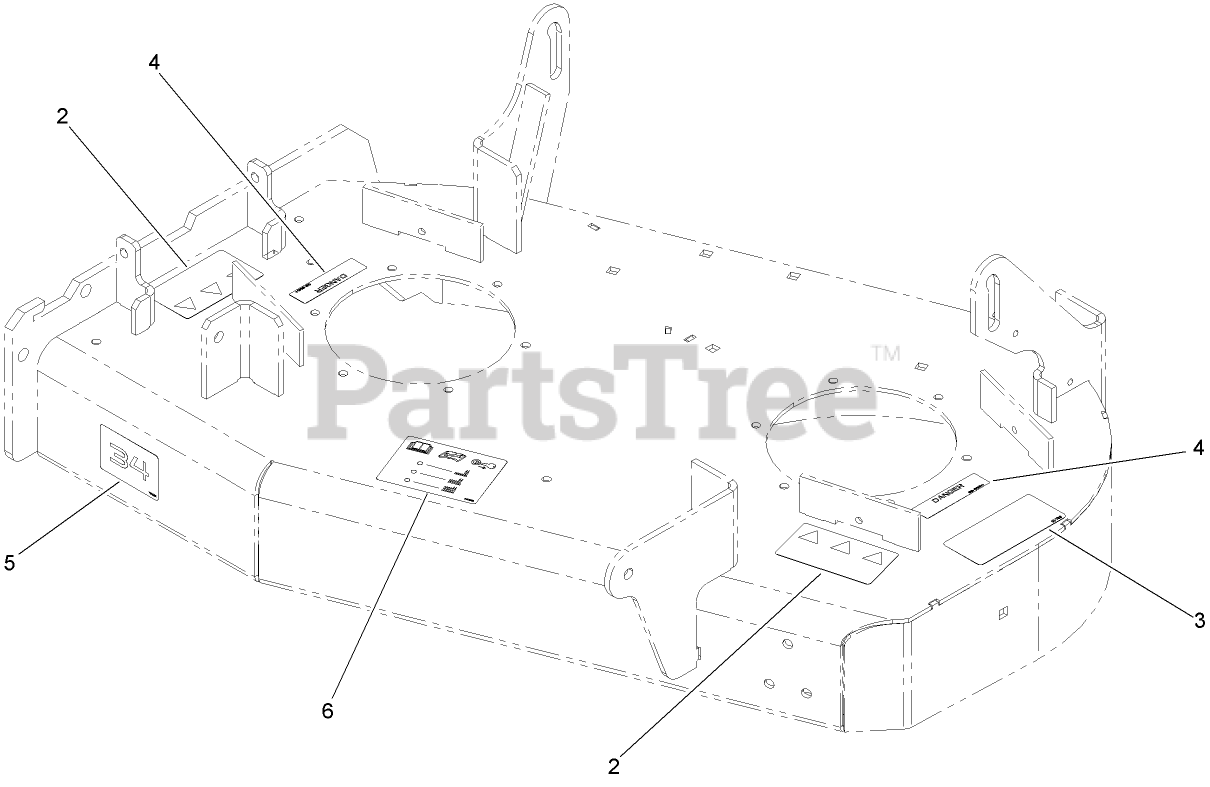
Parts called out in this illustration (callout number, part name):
2	DECAL-DANGER
3	DECAL-TORQUE, BLADE BOLT
4	DECAL-WARNING
6	DECAL-SCALP, ANTI
